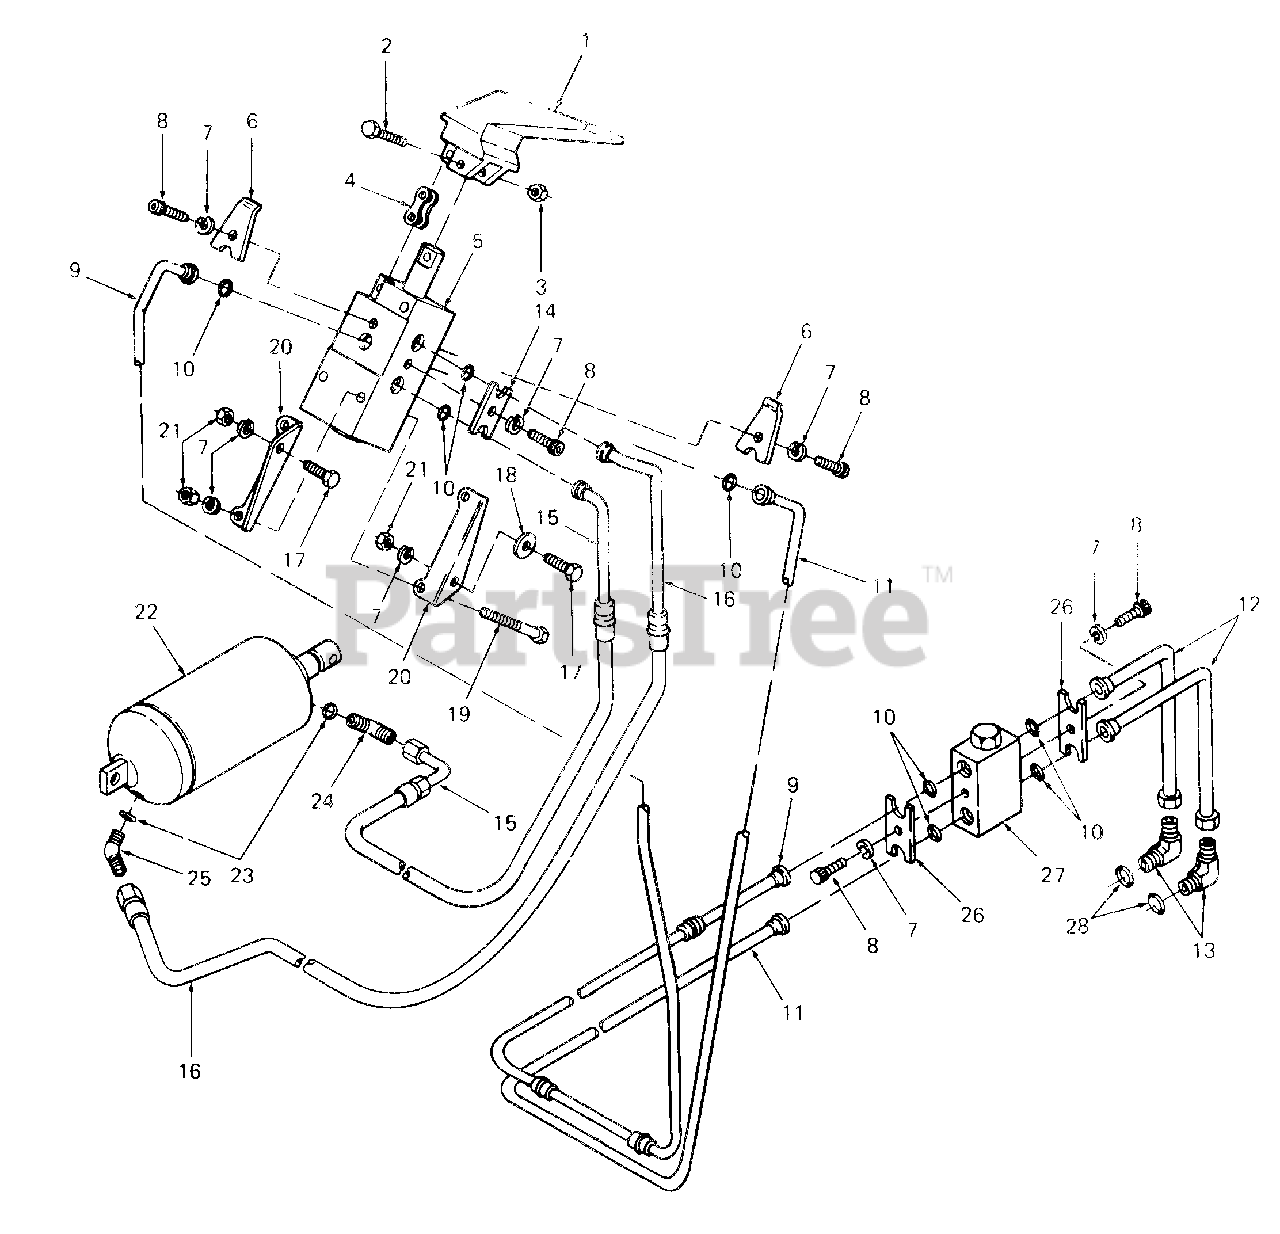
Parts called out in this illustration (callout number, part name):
1	Handle, Valve
2	Screw, Hex Cap, #10-24 X 1.0 Lg
3	Nut, Hex Center Lock, #10-24
4	Link, Chain
5	Valve, Lift
6	Clamp, Single
7	Washer, Lock, 1/4
8	Screw, Socket Hd Cap, 1/4-20 X .62 Lg GR8
9	Tube Assy, Return
10	O-Ring, .301 X 070 Dia
11	Tube Assy, Pressure
12	Tube Assy, Adapter
13	Elbow, Tube, 90 Degree
14	Clamp, Double
15	Hose, Cylinder -- Contracting
16	Hose, Cylinder -- Extending
17	Screw, Hex Cap, 1/4-20 X .62 Lg GR5
18	Washer, Bell, .265 X .75 X .062 Thk
19	Screw, Hex Cap, 1/4-20 X 2 25 Lg
20	Bracket, Valve Mtg
21	Nut, Hex, 1/4-20 GR5
22	Cylinder, Hydraulic
23	O-Ring, 1/4 OD Tube
24	Elbow, 90 Degree w/0-Ring
25	Elbow, 45 Degree w/0-Ring
26	Clamp, Valve Side
27	Valve, Relief
28	O-Ring, 3/8 OD Tube
